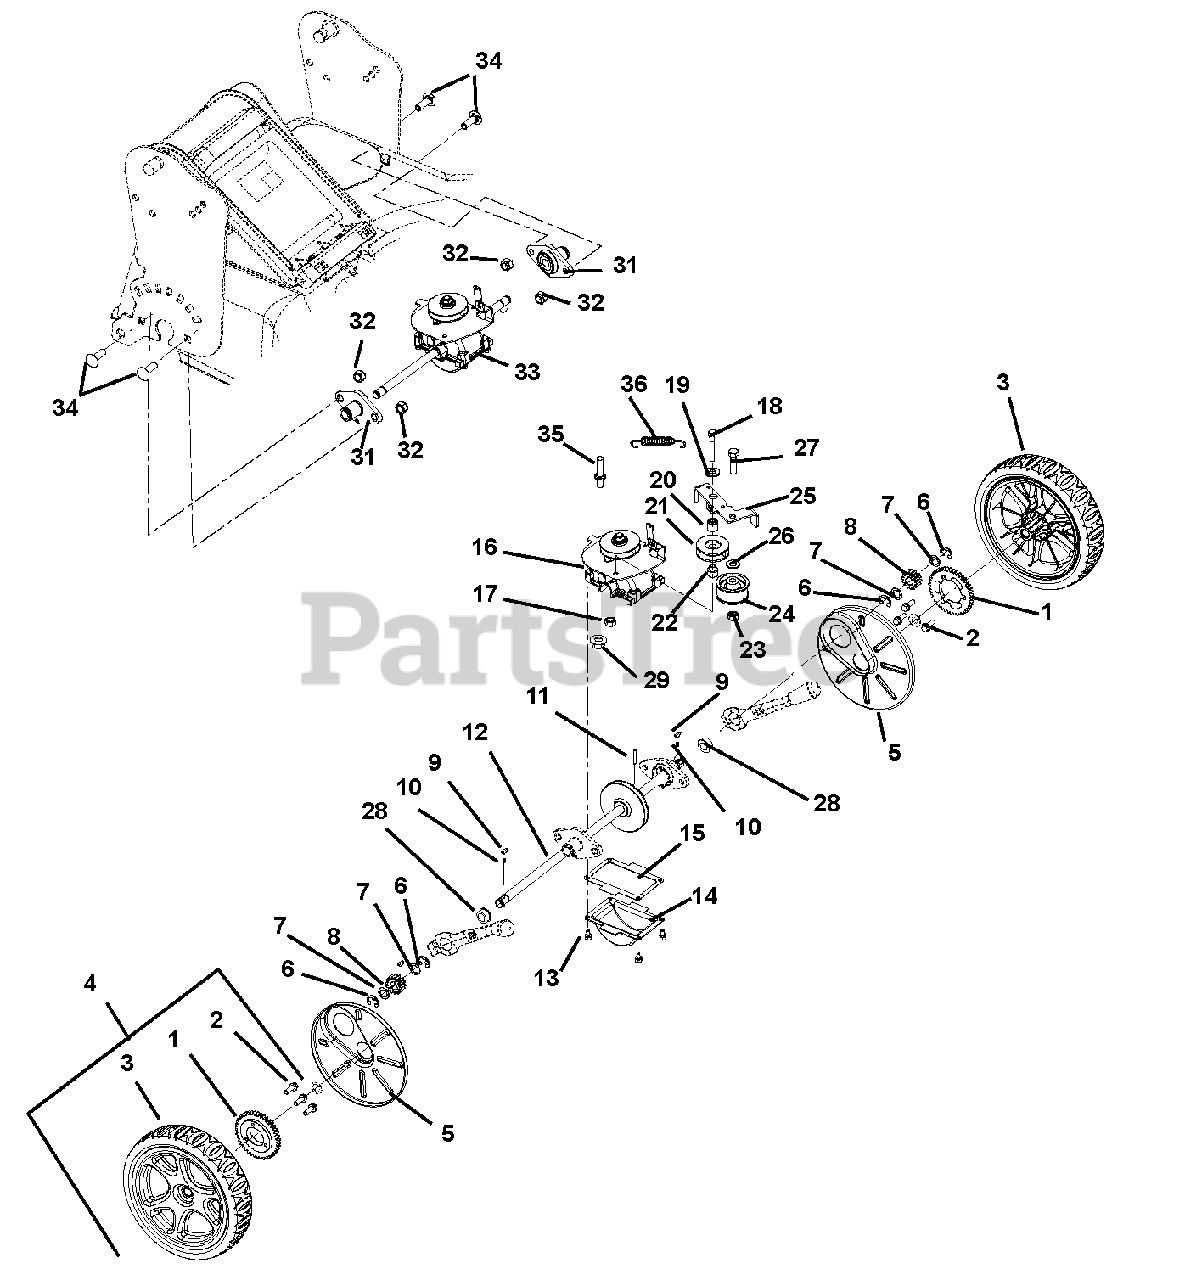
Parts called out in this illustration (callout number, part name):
1	Gear, Wheel (Order as part of kit 51111000. See item 4.)
2	Screw, Tapping .25-15x.75 Hi-Lo Hex Washer Head (Order as part of kit 51111000. See item 4.)
3	Wheel (Order as part of kit 51111000. See item 4.)
4	Kit, Assembly, LM Rear Wheel (Contains items 1, 2 and 3)
5	Wheel Cover
6	Ring, Retaining External .500 x .042
7	Washer, .500 x .750 x .020 Thrust
8	Pinion, WBLM Drive
9	Key, Woodruff .125 x .50 x .20
10	Spring, .134 x .186 x .144 Compression
11	Pin, Roll .156 x 1.00
12	Shaft, Transmission Output
13	Screw, Tapping 10-24 x .375 Hex Washer Head
14	Sump, Gearbox
15	Gasket, Transmission
16	Kit, WBLM Transmission Housing
17	Nut, Locking Top Flange .25-20
18	Bolt, Hex .25-20 x 2.00 Grade 5
19	Washer, Flat Steel .328 x 1.0 x .094
20	Spacer, .390 x .75 x .189
21	Idler, 3L Front Side .38 x 1.875
22	Spacer, Idler Pulley
23	Nut, Locking Center .38-16
24	Idler, Flat 1.875 OD x .75 Wide
25	Arm, Transmission Idler
26	Washer, Flat Steel .406 x .812 x .065
27	Bolt, Hex .38-16 x 1.38 Grade 5
28	Bushing, Transmission Output Shaft
29	Nut, Locking Flange .250-20
30	Bracket, Transmission Control
31	Kit, Wheel Mount Hub Service
32	Nut, Locking Top Flange .31-18
33	Kit, Transmission Service
34	Bolt, Round Head Square Neck .31-18 x 1.00 Grade 5
35	Belt, Finger
36	Spring, Tension .051 x .60 x 2.25
